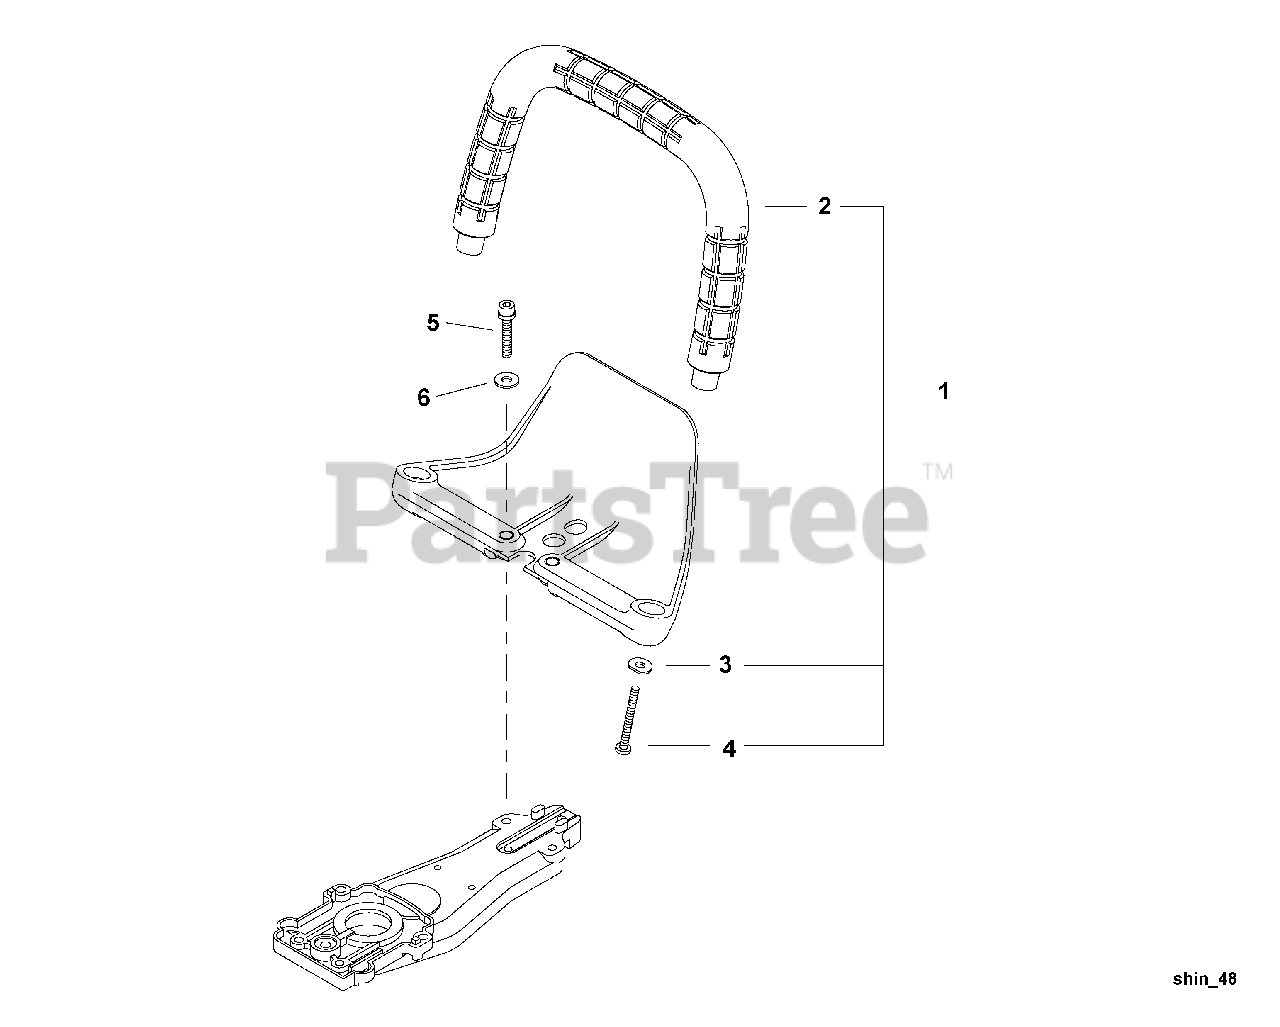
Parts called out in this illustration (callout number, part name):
1	HANDLE ASSY - FRONT
2	HANDLE - FRONT
4	SCREW - 5 -- TAPPING
5	SCREW - 6X30
